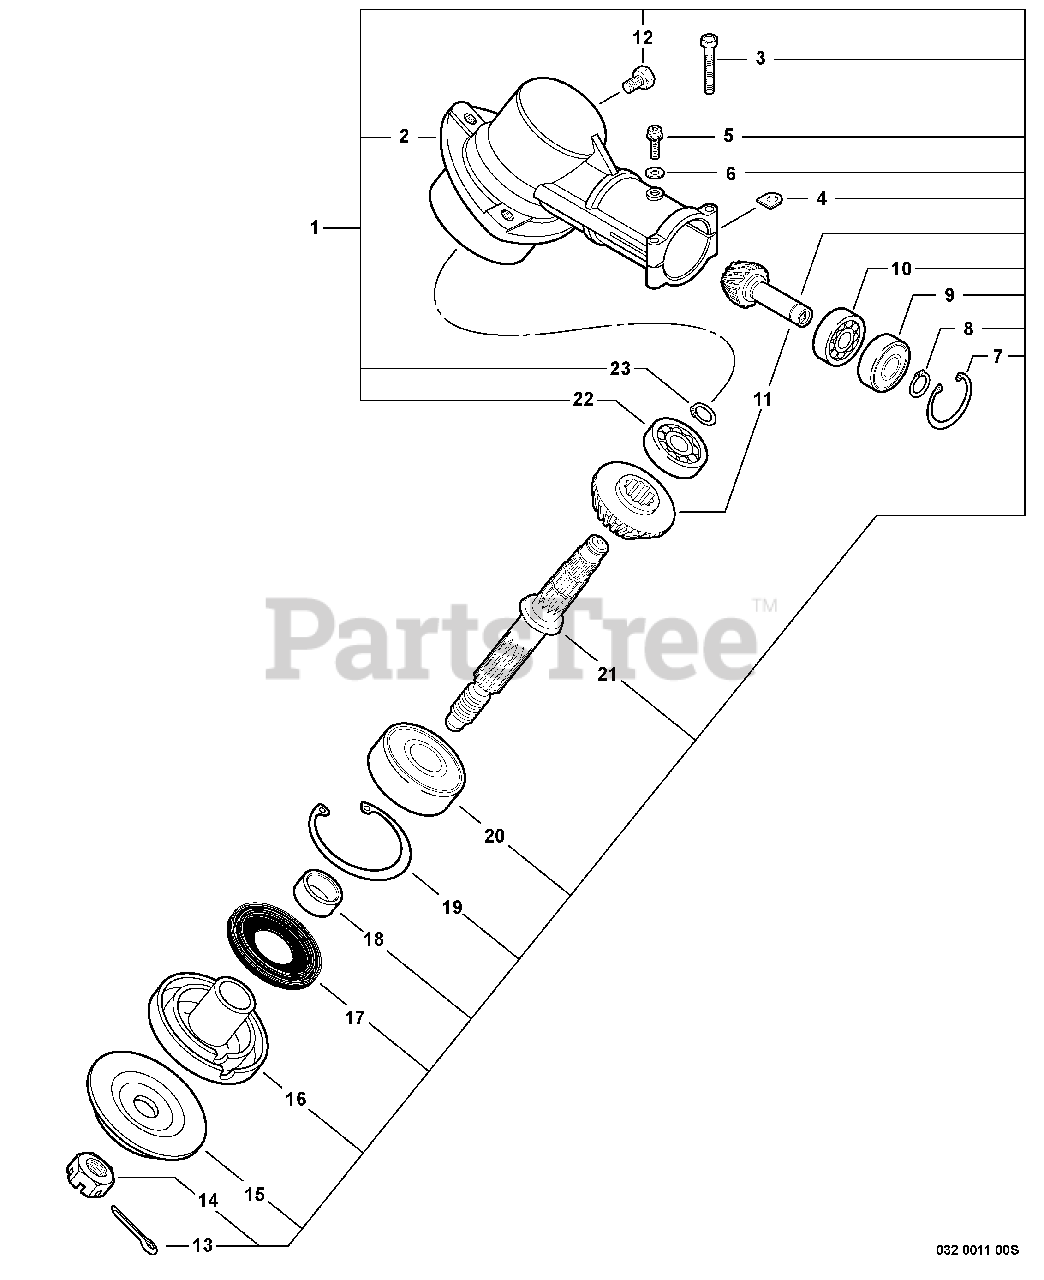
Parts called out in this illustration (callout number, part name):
1	GEAR CASE ASSY
2	HOUSING, GEAR CASE
3	BOLT 5×35 SP
5	SCREW 5×10
6	WASHER, FLAT 5.5×10×0.8
7	RING, SNAP Ø22
8	RING, SNAP Ø10
9	BEARING, BALL 6900Z
10	BEARING, BALL 6900
11	GEAR SET
12	BOLT M8×8
13	PIN, COTTER 2×22
15	PLATE, ADAPTOR - LOWER
16	PLATE, ADAPTOR - UPPER
17	SEAL, OIL 22
18	SPACER 11.8×15×9
19	RING, SNAP Ø32
20	BEARING, BALL - 6201 C3
21	SHAFT, GEAR
22	BEARING, BALL 609
23	RING, SNAP Ø12
